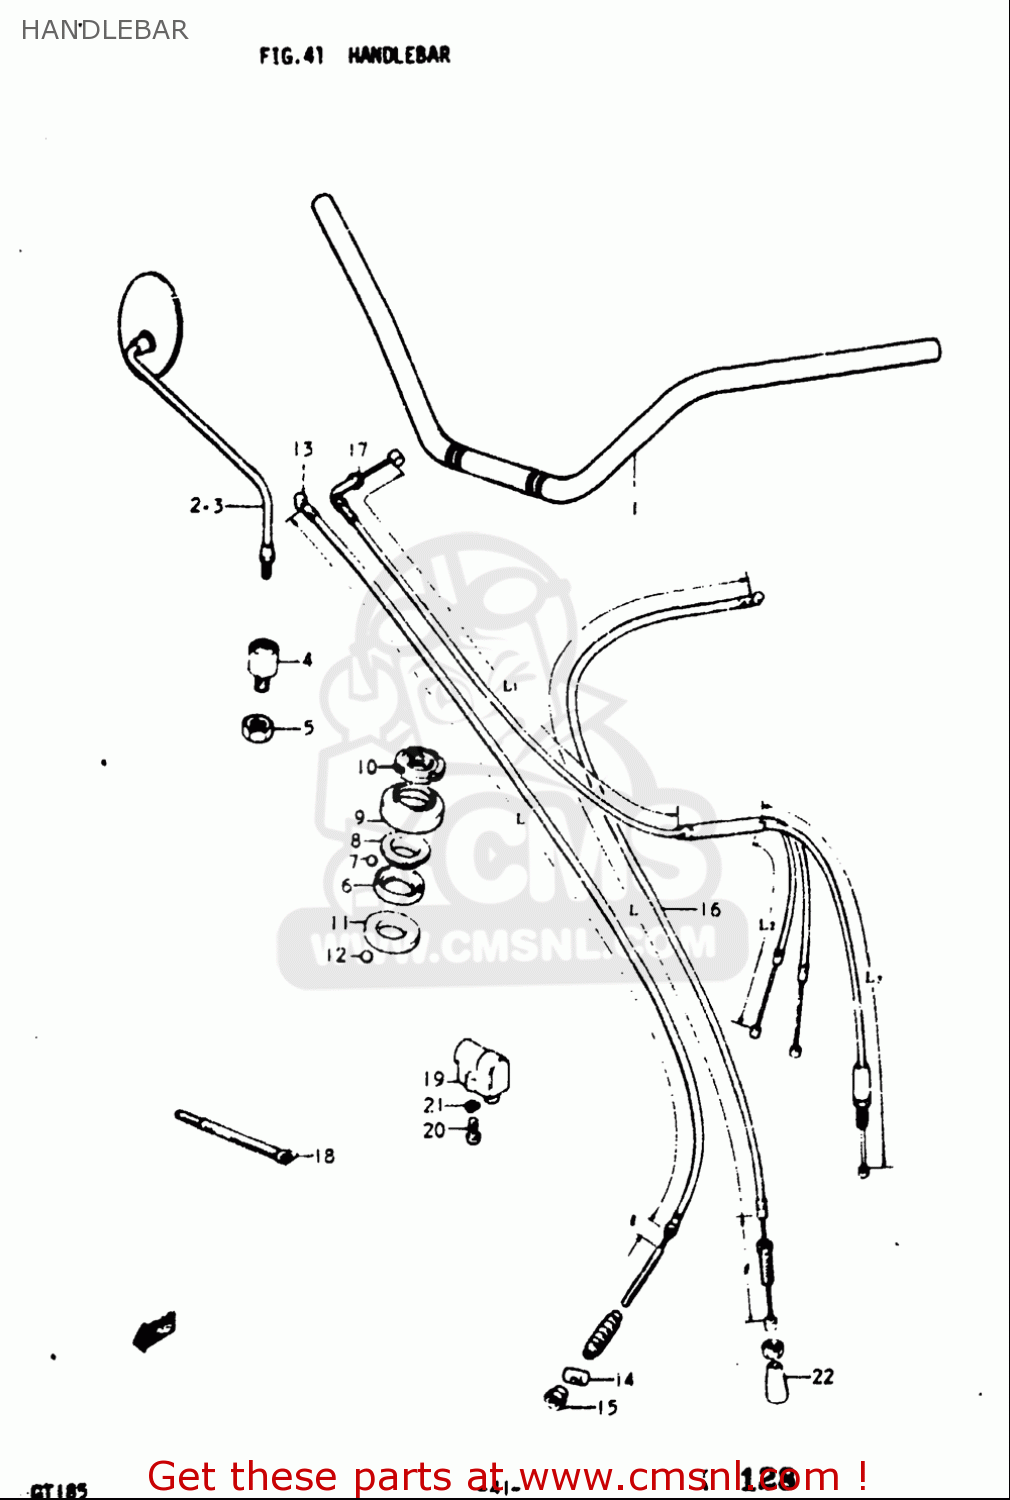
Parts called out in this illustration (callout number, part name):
1	HANDLEBAR
2	MIRROR ASSY,RE
3	MIRROR ASSY,LEFT
4	CUSHION ASSY,RR VIEW MIRROR
5	NUT
6	RACE,STEERING INNER UPR
7	BALL
8	RACE,STEERING OUTER UPR
10	NUT,STEERING STEM(25X44X10)
11	LACE,STEERING INNER LWR
12	BALL
13	CABLE,FRONT BRAKE
14	PIN(13X18)
15	NUT
16	CABLE ASSY,CLUTCH
17	CABLE ASSY,THROTTLE
18	CLAMP
19	LOCK ASSY,STEERING
20	SCREW
21	WASHER,LOCK
22	SEAL,DUST(7X18X30)
